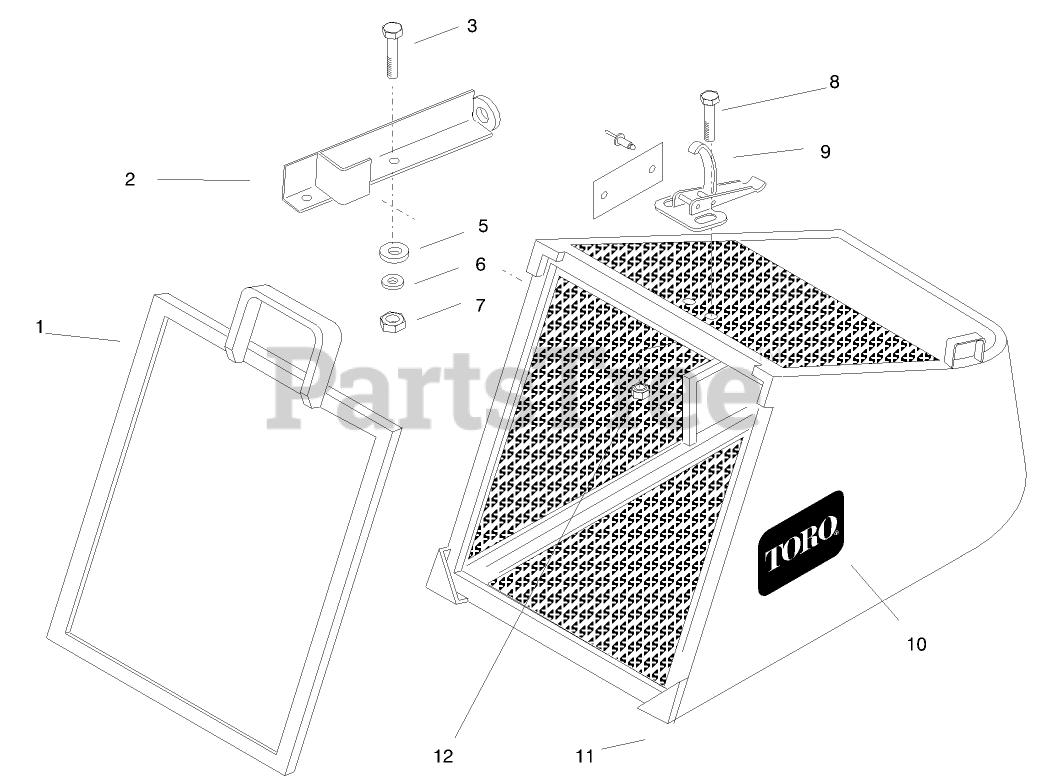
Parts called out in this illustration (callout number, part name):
2	BRACKET - MOUNTING
3	SCREW-HH
5	NUT-LOCK, NI
6	WASHER-LOCK
7	NUT-HEX
9	CLAMP-SLOTTED
10	DECAL
11	Hopper Decal (Incl. Ref. #10
12	NUT-HEX, KEPS
